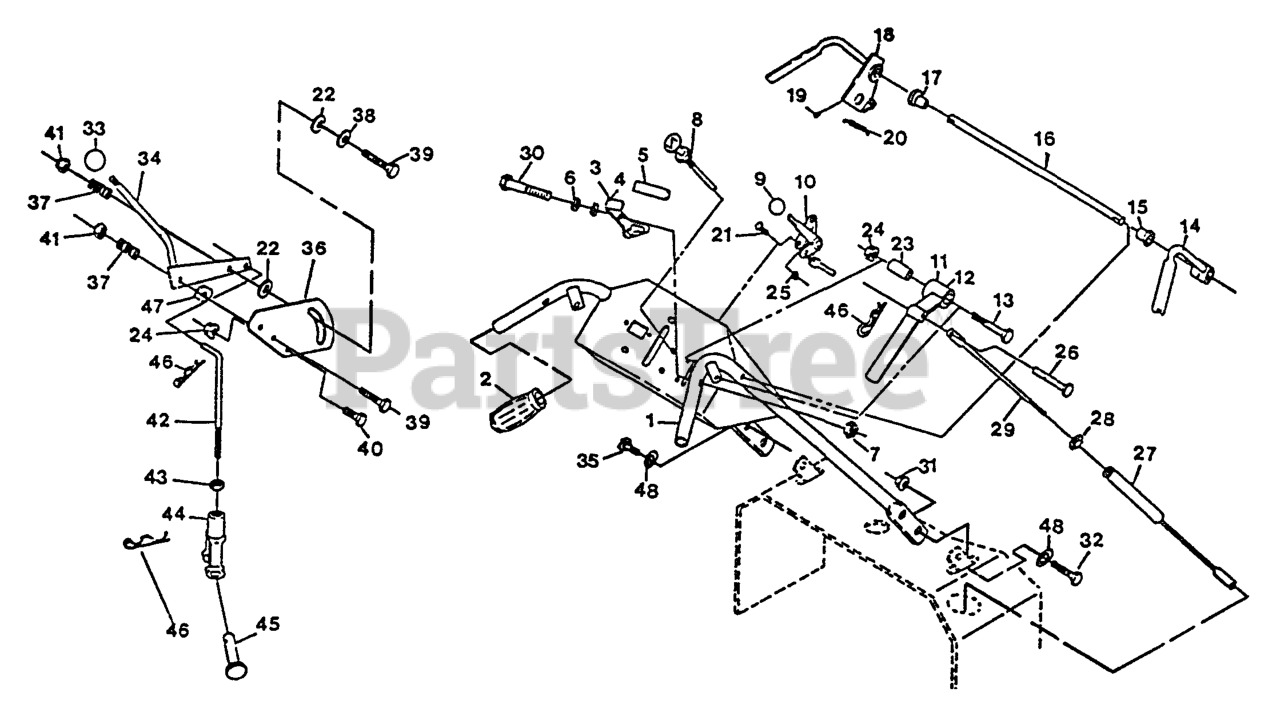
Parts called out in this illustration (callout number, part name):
3	LH LATCH W/GRIP
4	RH LATCH W/GRIP
5	GRIP-LATCH
6	WASHER-SPRING
8	CONTROL-CHOKE
9	KNOB-BALL
15	BUSHING-NYLON
16	ROD,CONNECTING
17	BUSHING,FLANGED
19	SCREW-SET
20	SPRING-EXTENSION
21	BOLT-CARR
22	WASHER-FRICTION
23	BUSHING-LEVER, DRIVE
26	PIN-CLEVIS
27	WLD,HOUSING
33	KNOB-BALL
36	PLATE-LEVER, SHIFTER
37	SPRING-COMPRESSION
38	WASHER-FRICTION
42	ROD,SPEED CONTROL
44	YOKE-ADJUSTABLE
45	PIN-CLEVIS
46	PIN-COTTER
